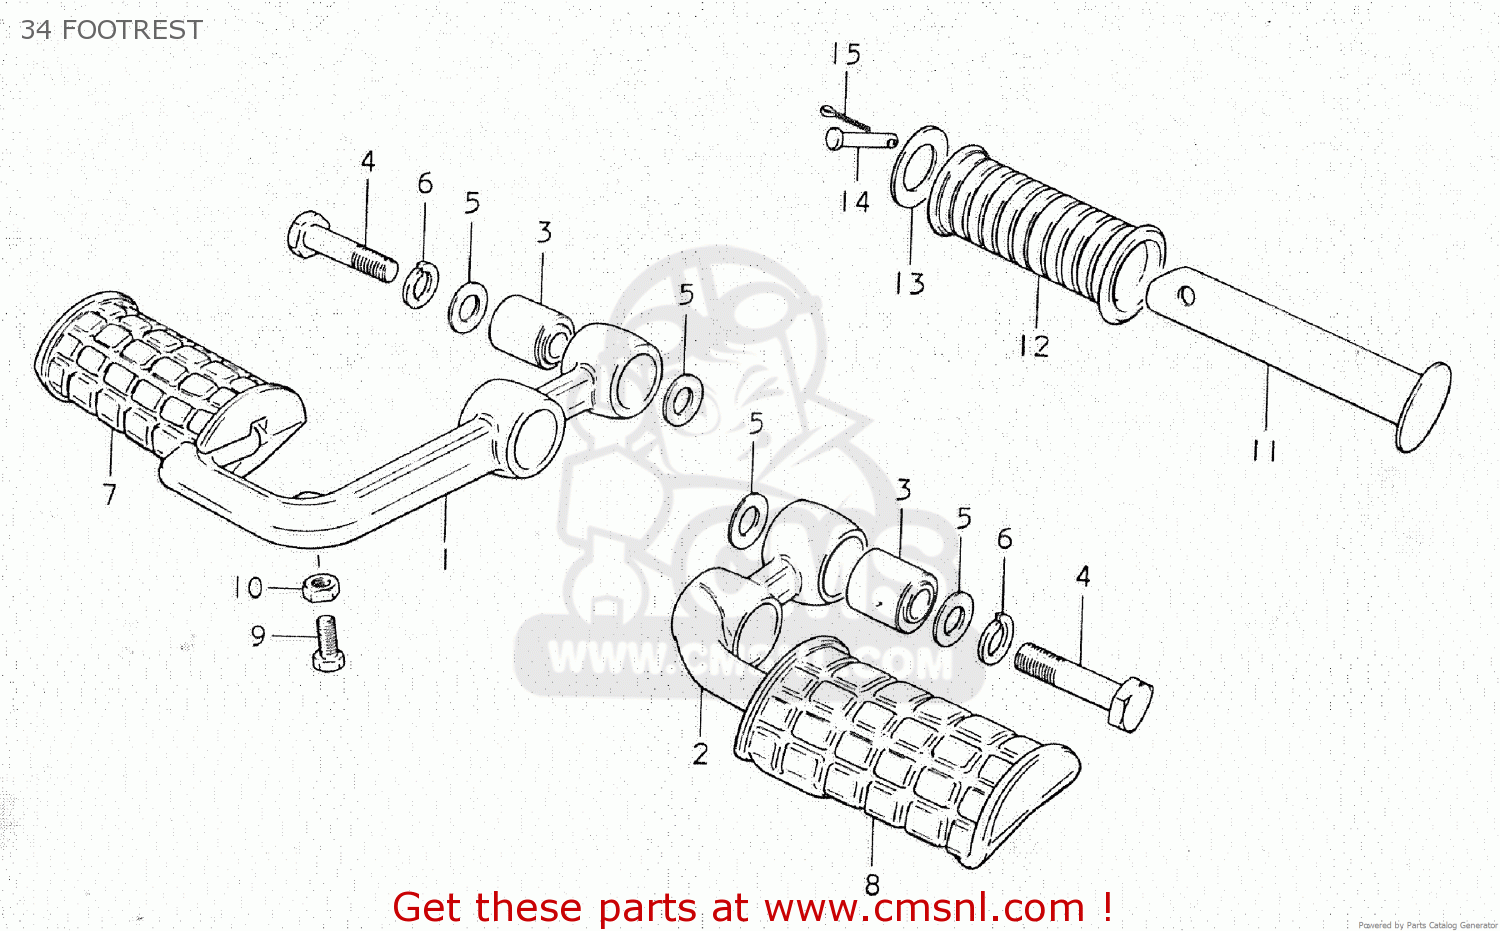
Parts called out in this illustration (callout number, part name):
1	BAR,FRONT FOOTREST,RIGHT
2	BAR,FRONT FOOTREST,LEFT
3	BUSH
4	BOLT
5	WASHER (10.1X21X2.3)
6	LOCK WASHER
7	RUBBER,FR FOOTREST,R
8	RUBBER,FOOTREST
9	BOLT
10	NUT 6MM
11	BAR,FOOTREST RUBBER
12	RUBBER,PILLION FOOTREST
13	WASHER (19.5X32X2)
14	PIN
15	PIN 20X20
